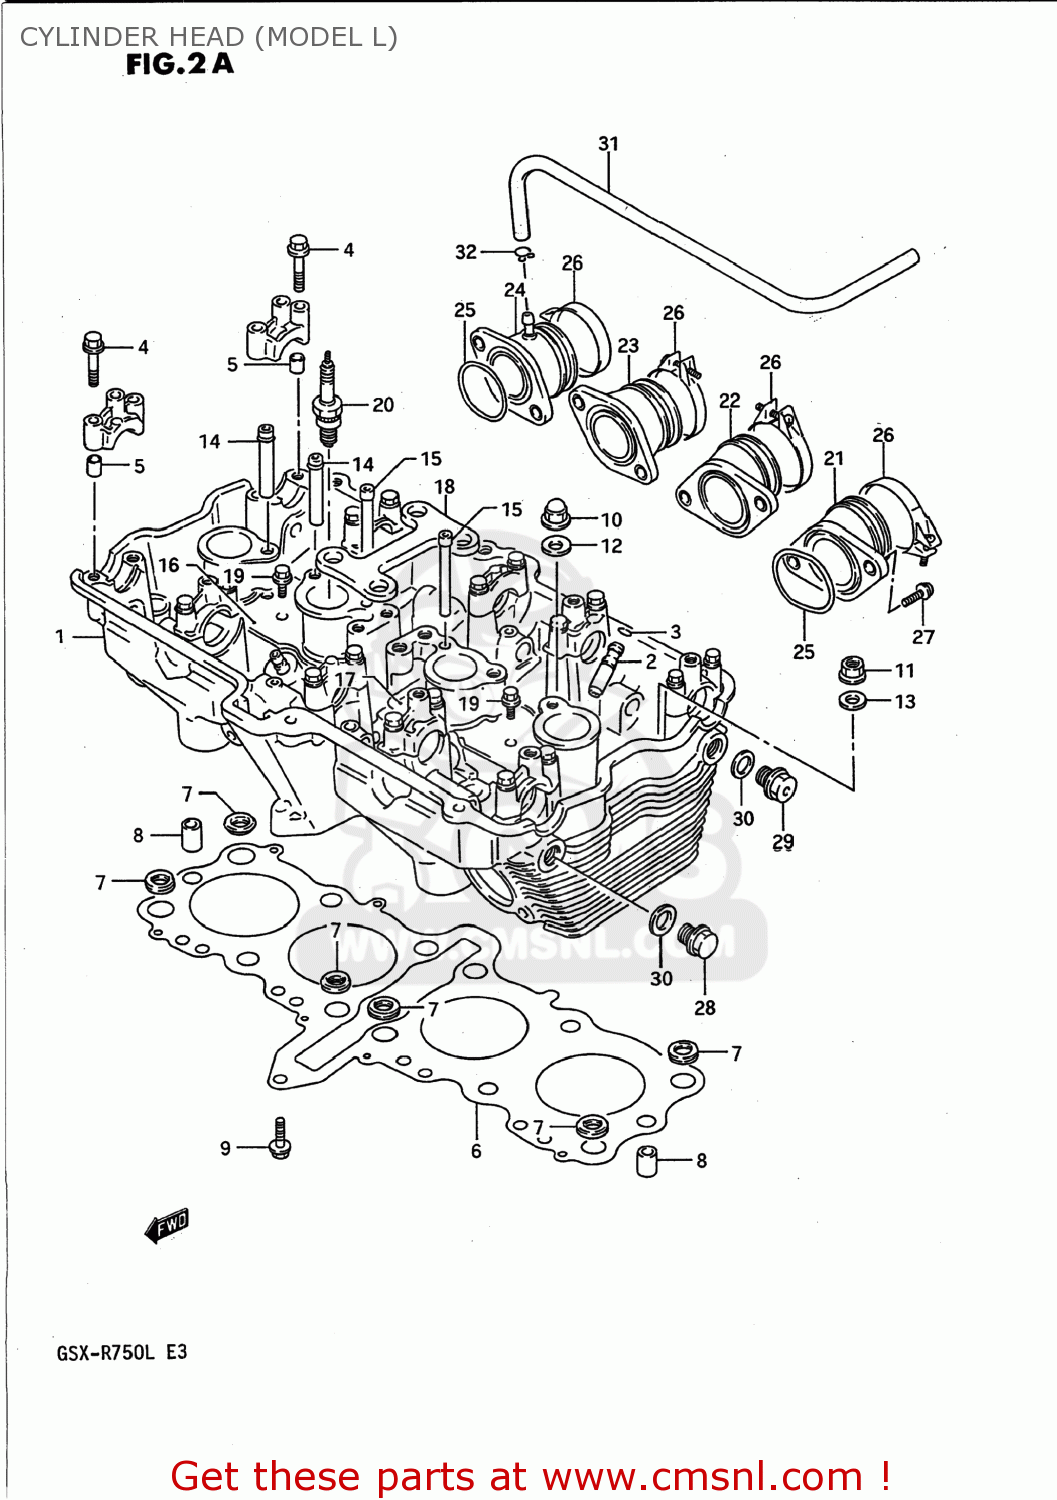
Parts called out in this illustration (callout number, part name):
1	HEAD ASSEMBLY,CYLINDER
2	GUIDE,VALVE
3	RING,SNAP
4	BOLT(6X39)
5	PIN(6.2X8X11)
6	GASKET,CYLINDER HEAD
7	O RING,HEAD GASKET
8	PIN
9	BOLT 6X30
10	NUT
11	NUT
12	GASKET(10.2X20X2).3 (NAS)
13	WASHER (10.5X22X2.3)
14	PIPE,OIL NO.1
15	PIPE,OIL NO.3
16	PLATE,OIL PIPE,R
17	PLATE,OIL PIPE,L
18	PLATE,HEAD REINF
19	BOLT
20	PLUG,SPARK(CR9EK)
21	PIPE,INTAKE
22	PIPE,INTAKE
23	NET,INTAKE
24	PIPE,INTAKE
25	O RING(D:2.4,ID:41.7)
26	CLAMP
27	SCREW
28	PLUG
29	PLUG
30	GASKET(14X19.2X2) (NAS)
31	HOSE
32	CLIP
